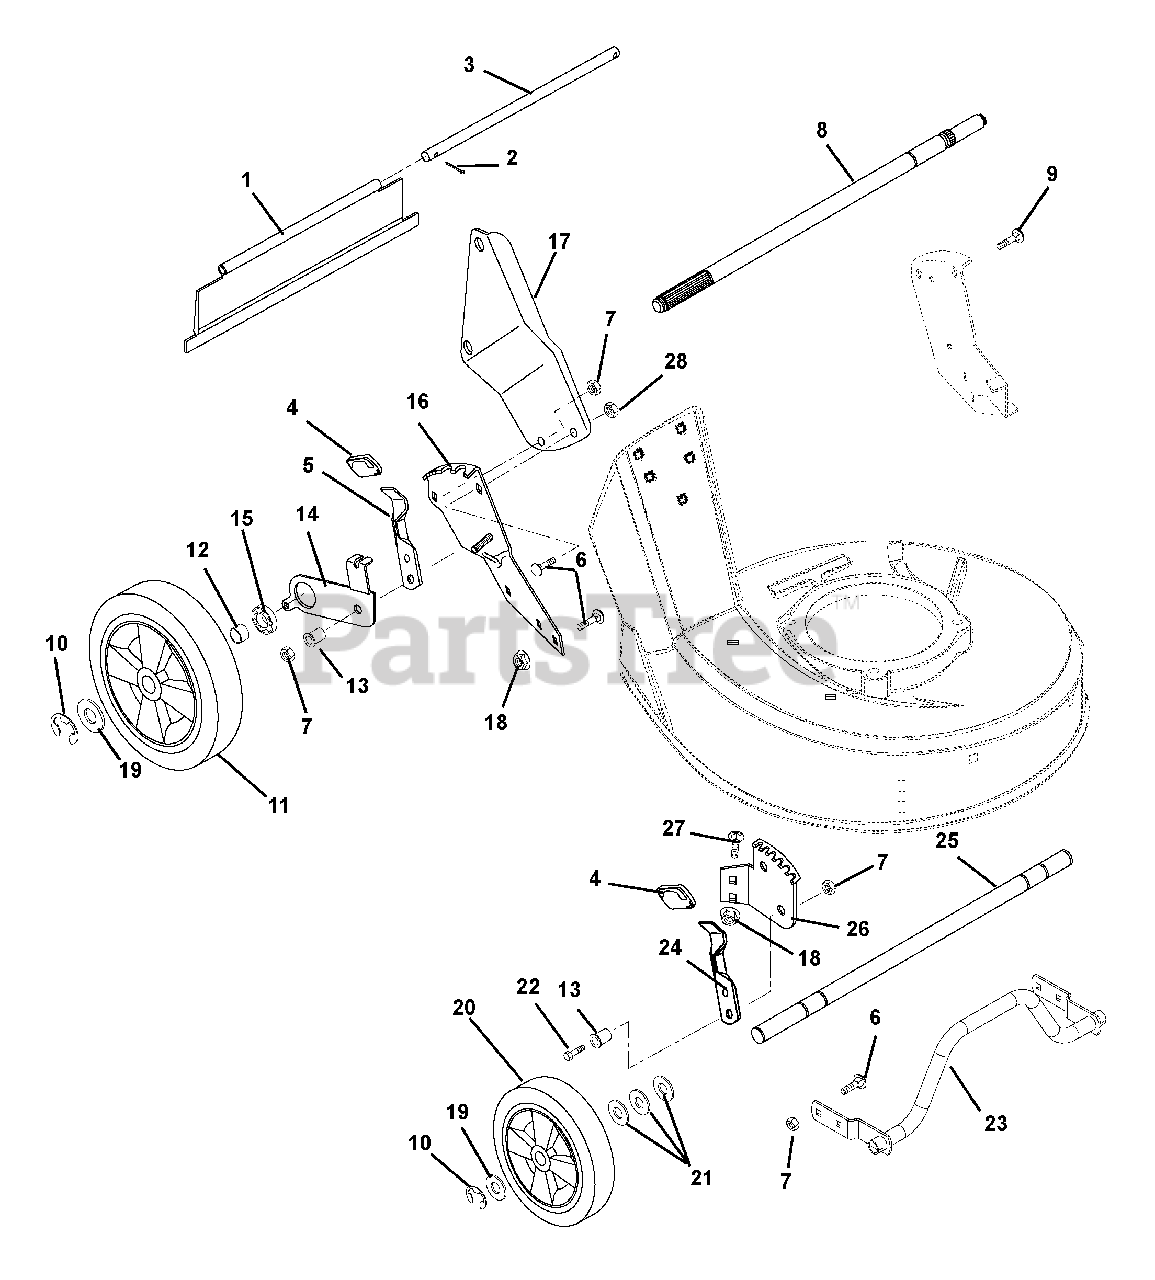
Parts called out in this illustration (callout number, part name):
1	Rear Protective Guard, Self Propelled
2	Pin, Cotter .06 x .50
3	Rod
5	Height Adjustment Lever
6	Bolt, Round Head Square Neck .31-18 x .62
7	Nut, Locking Center .31-18
8	Rear Axle
9	Bolt, Round Head Square Short Neck .31-18 x 1.00
10	Ring, Retaining External .50 x .042
11	Wheel, Left Hand Rear 10.50
11	Wheel, Right Hand Rear 10.50
11	Tire Skin 10.50 x 2.00
12	Spacer Tube
13	Bushing, Flange .312 x .50 x .344 x .88
14	Rear Adjustment Bracket Left Hand
14	Rear Adjustment Bracket Right Hand
14	REAR BRACKET AND BEARING ASSY RH
15	Bearing, Ball .625 x 1.38 x .50
16	Rear Quadrant, Left Hand
16	Rear Quadrant, Right Hand
17	Bracket, Handlebar Mounting-Right Hand
17	Bracket, Handlebar Mounting-Left Hand
18	Nut, Locking Flange .31-18
19	Washer, Flat Steel .505 x .88 x .072
20	Wheel 7.50-.50 Bore, 1.50 Hub
21	Washer, Flat Steel .520 x .827 x .062
22	Bolt, Hex .31-18 x 1.00 Grade 5
23	Guard, LM Valve Cover
24	Lever, Front Height Adjustment
25	Front Axle
26	Front Quadrant, Left Hand
26	Front Quadrant, Right Hand
27	Bolt, Round Head Square Neck .31-18 x .50 Grade 5
28	Nut, Locking Nylon .31-18
